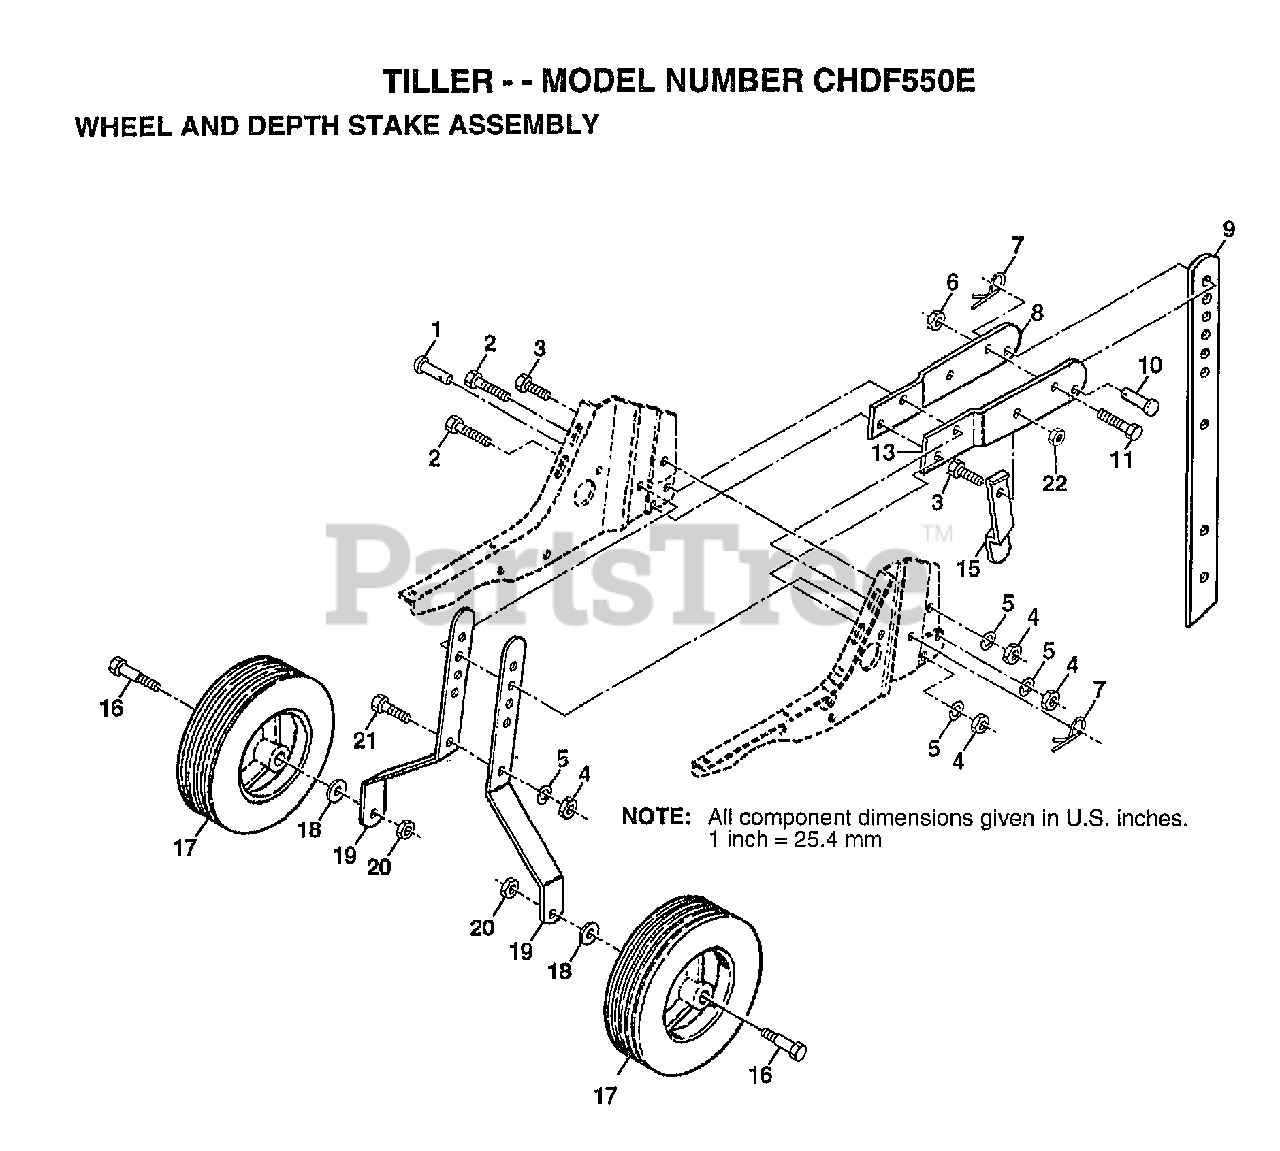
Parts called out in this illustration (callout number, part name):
1	DRILLED RIVET RT
3	BOLT
4	NUT.HEX.5/16-18
5	LOCKWASHER
6	NUT
7	SPRING.RETAINER
11	BOLT
15	STAKE SPRING TI
16	BOLT SHOULDER
18	WASHER
22	NUT
